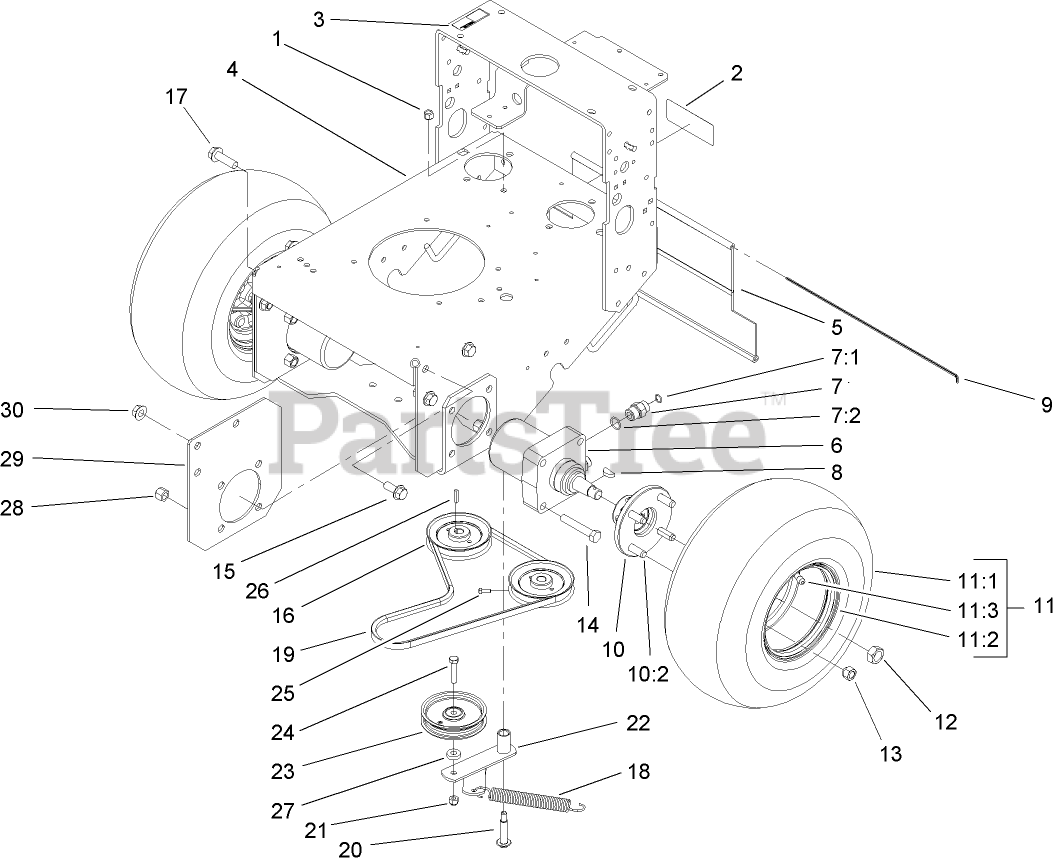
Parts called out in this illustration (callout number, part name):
1	NUT-LOCK
2	DECAL-CAUTION
3	DECAL-SHUT OFF, FUEL
4	FRAME ASM
5	SHIELD-TRAILING
6	HYD MOTOR ASM
7	FITTING-STRAIGHT
7:1	O-RING
7:2	O-RING
8	KEY-WOODRUFF
9	ROD-SHIELD
10	WHEEL HUB ASM
10:2	STUD-TYPE, DRIVE
11	WHEEL AND TIRE ASM
11:3	STEM-VALVE
12	NUT-MOTOR, WHEEL
13	NUT-LUG
14	SCREW-HH
15	SCREW-HHF
16	SHEAVE ASM
17	SCREW-HHF
18	SPRING-EXTENSION
19	BELT-V
20	BOLT-WHEEL
21	NUT-LOCK, NI
22	IDLER LEVER ASM
23	PULLEY-IDLER
24	SCREW-HH
25	SCREW-SET
27	Washer
28	NUT-HHF
29	PLATE-FRAME
30	NUT-HF
